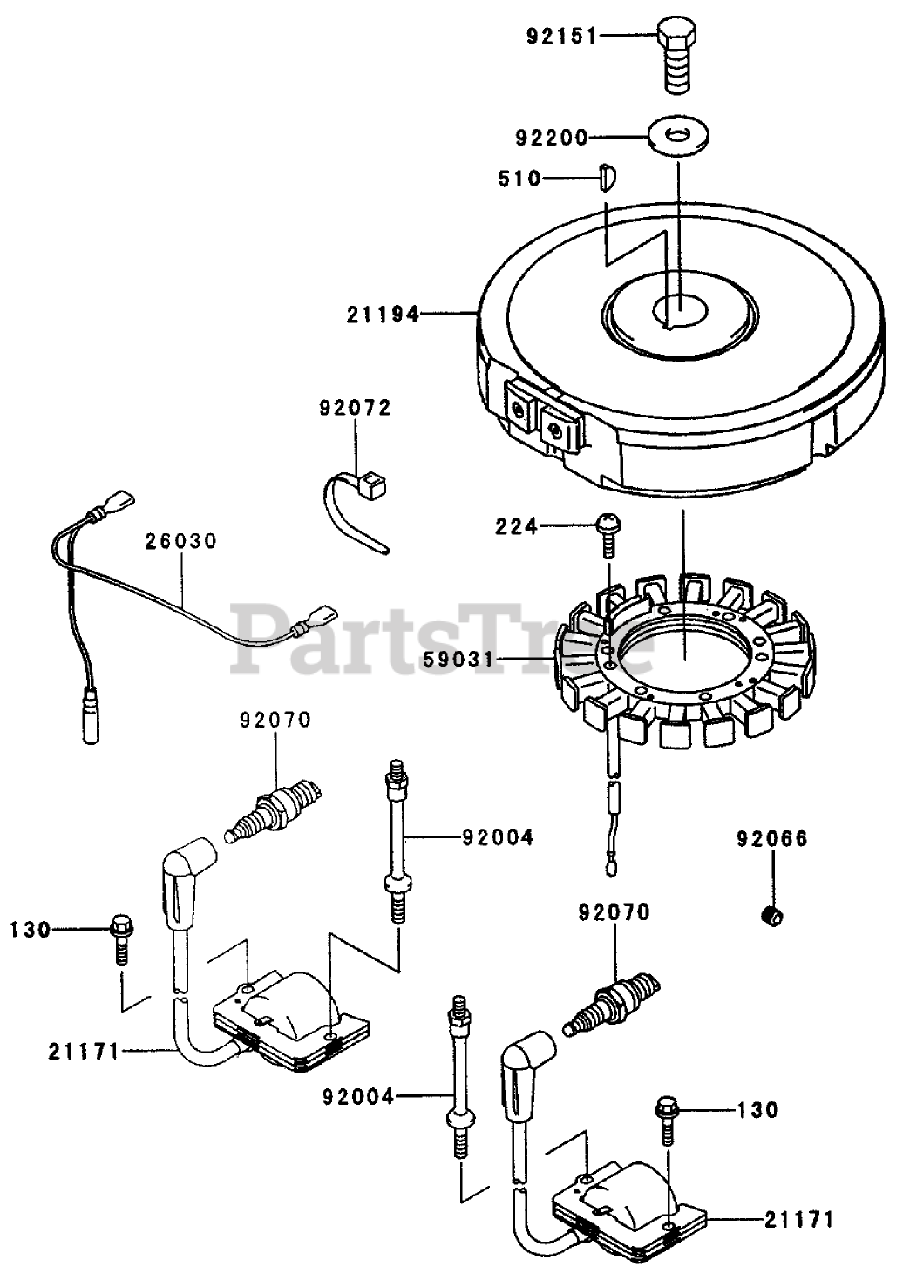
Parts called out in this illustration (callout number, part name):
2	CLAMP-CABLE
3	FILTER-FUEL
4	HARNESS-WIRE
5	NUT-LOCK, NI
6	WASHER-LOCK
7	NUT-HF
8	GROMMET
9	TUBE-RETAINER
10	WASHER
11	GROMMET
12	SPACER
13	STRAP-CLUTCH/BRAKE
14	SCREW-HH
15	WASHER-PLAIN
16	SCREW-HH
17	WASHER-FLAT
18	SCREW-HH
19	WASHER
21	CLUTCH/BRAKE
22	PULLEY-DRIVE
23	KEY-SQUARE
24	COVER-PULLEY
25	DECAL-SURFACE, HOT
26	MUFFLER
27	Clamp-Muffler
28	NIPPLE
29	CAP-PIPE
